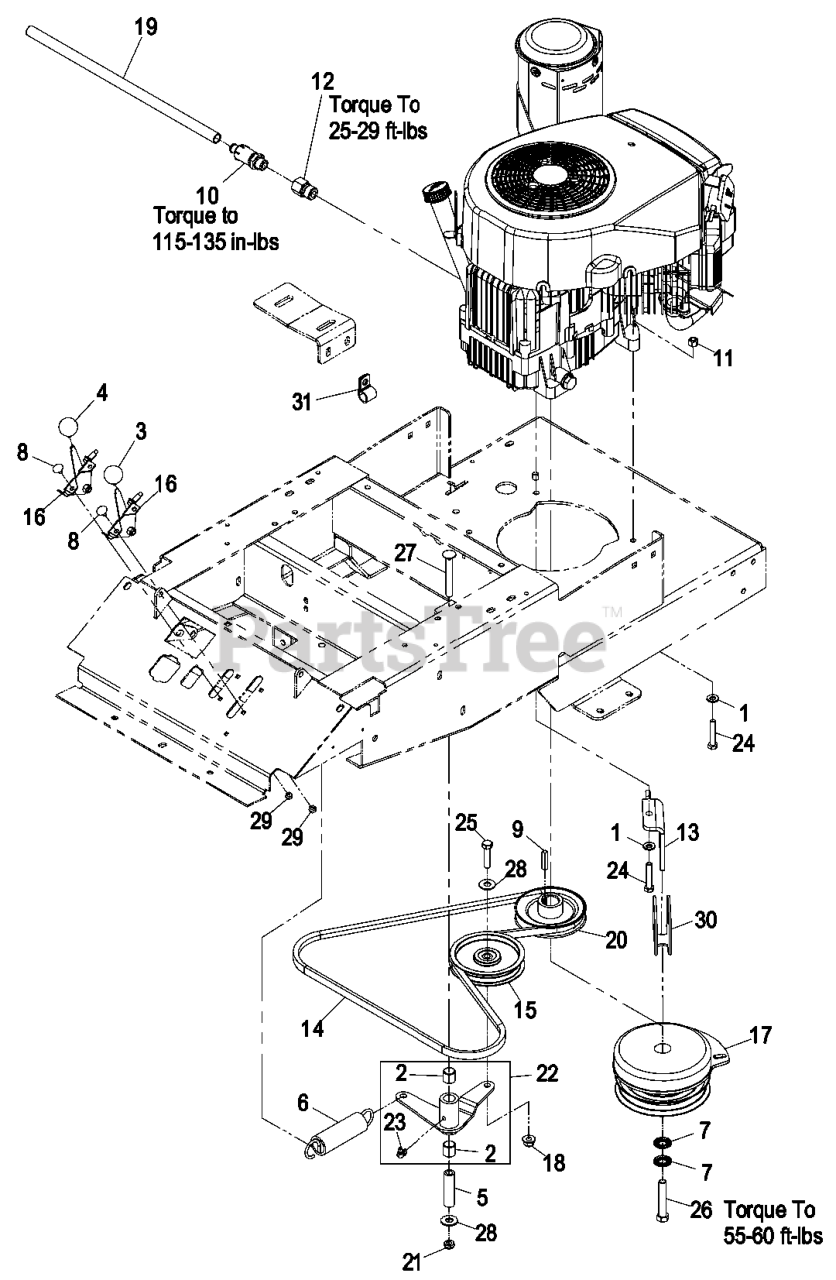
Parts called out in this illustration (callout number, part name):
1	WASHER-SPRING
2	SLEEVE-BEARING
3	KNOB-BALL
4	KNOB-BALL, BLACK
5	BUSHING-PIVOT, IDLER
6	SPRING-EXTENSION
7	WASHER-SPRING
8	BOLT-CARR
9	KEY-SQUARE
10	VALVE-DRAIN, OIL
11	NUT-LOCK, NI
12	ADAPTER
13	ROTATION-STOP, CLUTCH
14	BELT-V
16	THROTTLE CONTROL ASM
18	NUT-HF, NI
19	TUBE-DRAIN, OIL
22	IDLER HYDRO ASM
23	FITTING-GREASE, 90 DEG
24	SCREW-HH
25	SCREW-HH
26	SCREW-HH
27	SCREW-CARR
28	WASHER-FLAT
29	NUT-LOCK, NI
31	CLIP-LOOM
